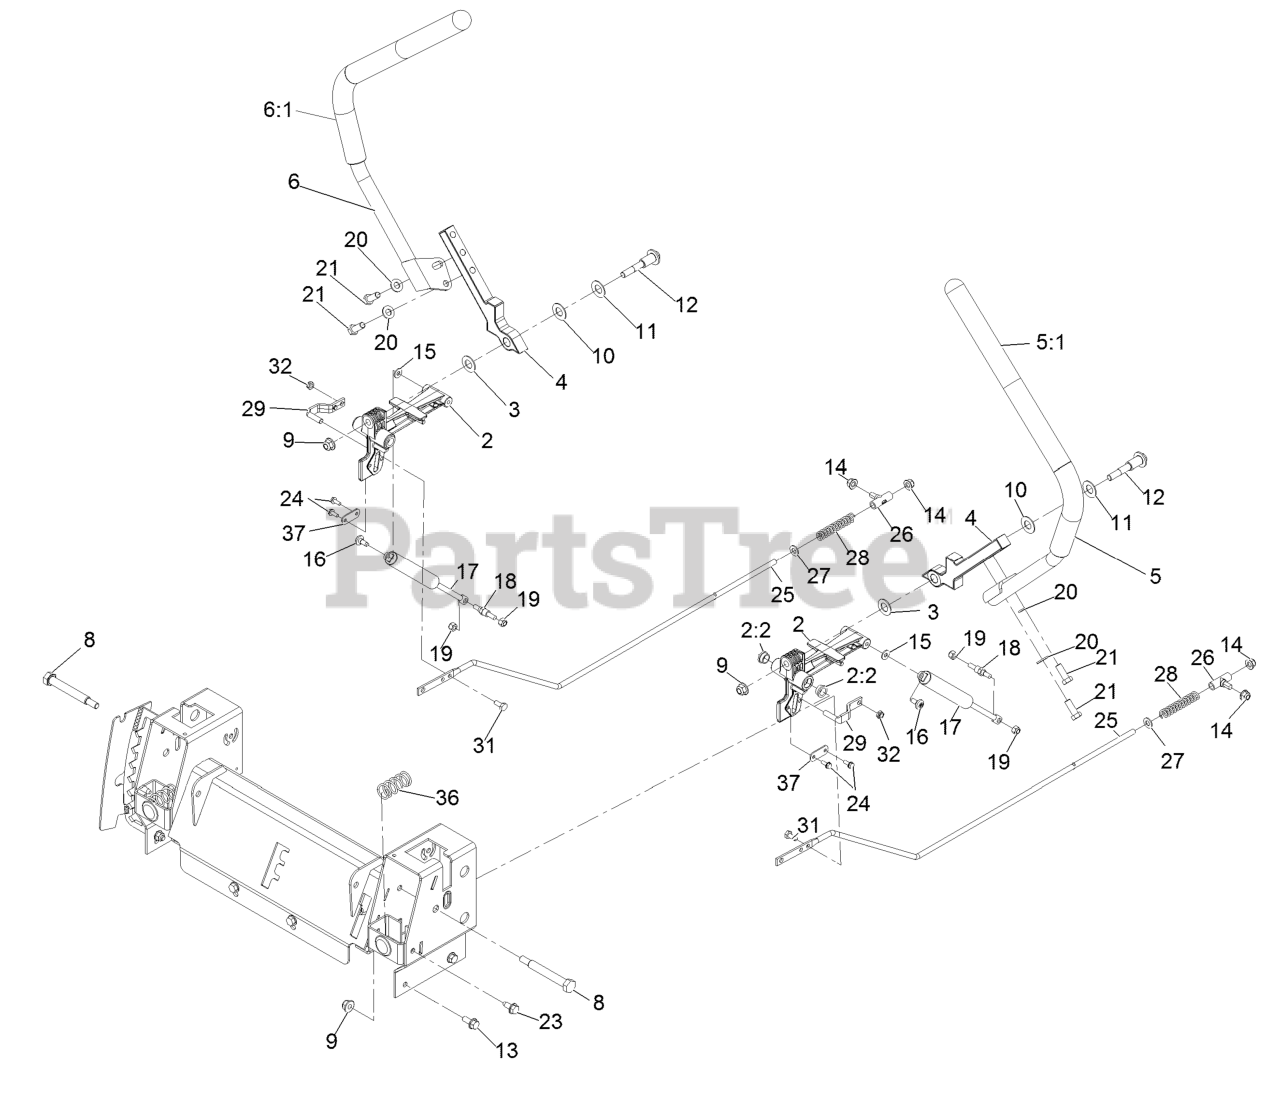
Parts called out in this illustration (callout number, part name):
2	Actuator Arm ASM
2:2	Bushing-Flange
3	Washer-Nylon
4	Arm-Control
5	Handle-Control, LH
6	Handle-Control, RH
8	Bolt-Pivot
9	Nut-Nyloc 3/8-16 Flg
11	Washer-Belleville
12	Bolt-Pivot
13	Screw-HH Flg 5/16-18 X 3/4
14	Nut-Nyloc 5/16-18 Flg
16	Screw-1/4-20 X 1/2 Tf Torx Plus
18	Stud-Damper
19	Nut-Nyloc 1/4-20
20	Washer-3/8 SAE
21	Screw-HH 3/8-16 X 1
23	Screw-HWH 5/16-18 X 3/4 Tf
24	Screw-HWH #10-24 X 1/2 Taptite
25	Rod-Hydro
26	Mount-Rod, Hydro
27	Washer-5/16 SAE
29	Pin-Rod, Hydro
31	Screw-HH 1/4-20 X 5/8
32	Nut-Nyloc 1/4-20 Thin
36	Spring-Return
37	Plate-Stop, Hydro
